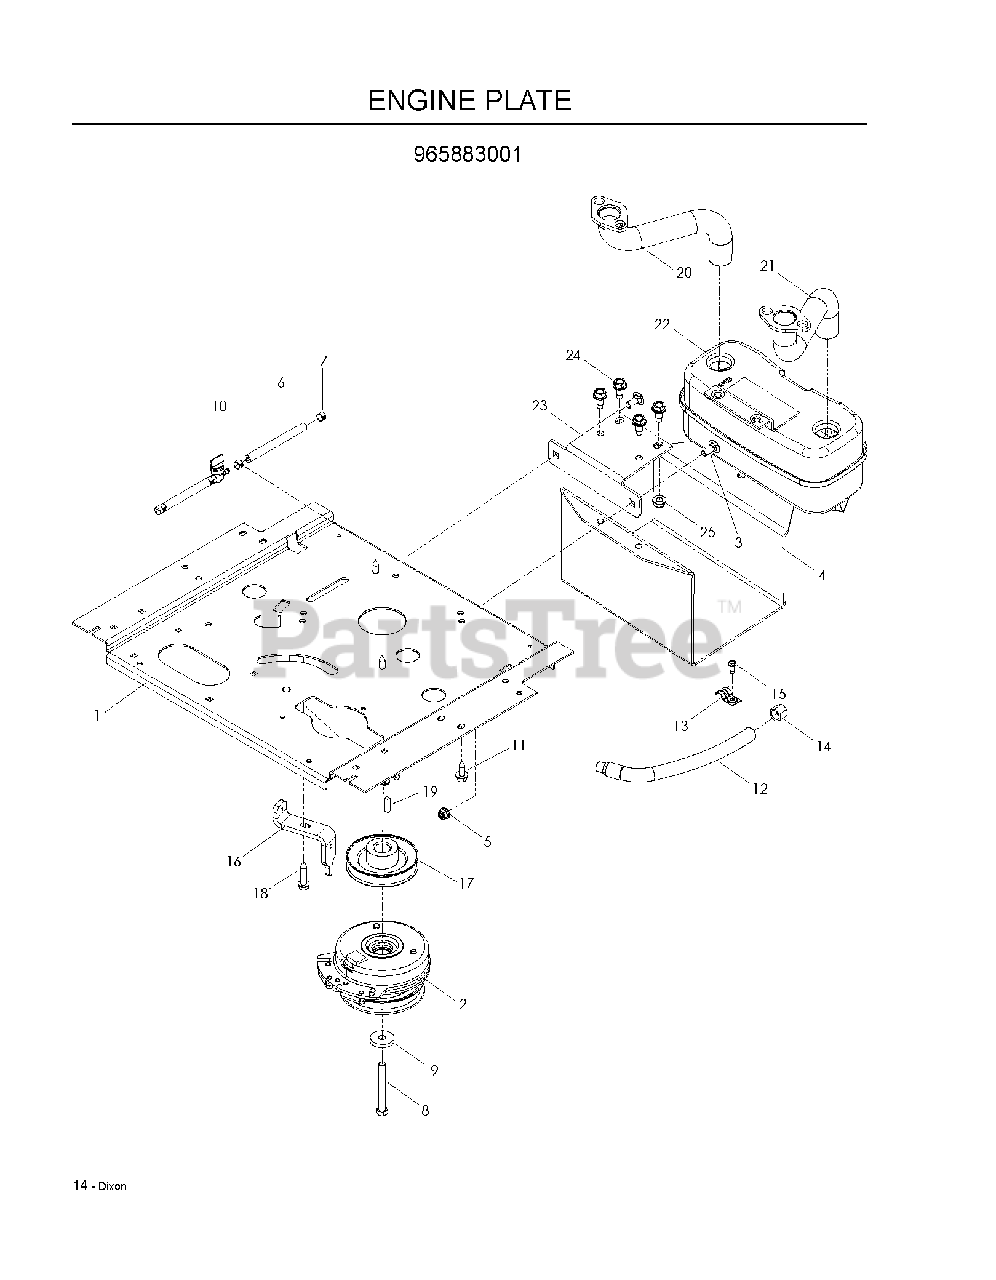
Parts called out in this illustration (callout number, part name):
1	PLATE, ENGINE, BLACK
2	CLUTCH, ELECTRIC
3	RHSNB 5/16C X 1
4	GUARD, MUFFLER, BLACK
5	NUT 5/16 NYLOC
6	FUEL LINE 5"
7	HOSE CLAMP
8	HCS 7/16-20X3-1/2 GR 5 ZN
9	CLUTCH, WASHER
10	FUEL VALVE
11	HHFS 3/8-16 X 1.0 THD FORMING
12	OIL DRAIN HOSE
14	DRAIN CAP
15	SCREW 1/4 X 5/8
16	STOP, CLUTCH BLK
18	BOLT 3/8-16 X 1 1/2 ZINC CLEAR
19	KEY 1/4 SQ X 1.0
20	RP.EXHAUST.TUBE.LH.BS/TWIN
21	RP.EXHAUST.TUBE.RH.BS/TWIN
22	MUFFLER ASM TWIN
23	BRACKET, MUFFLER, BLACK
24	BOLT 5/16-18 X 3/4
25	5/16-18 NYLOC FLANGE NUT
